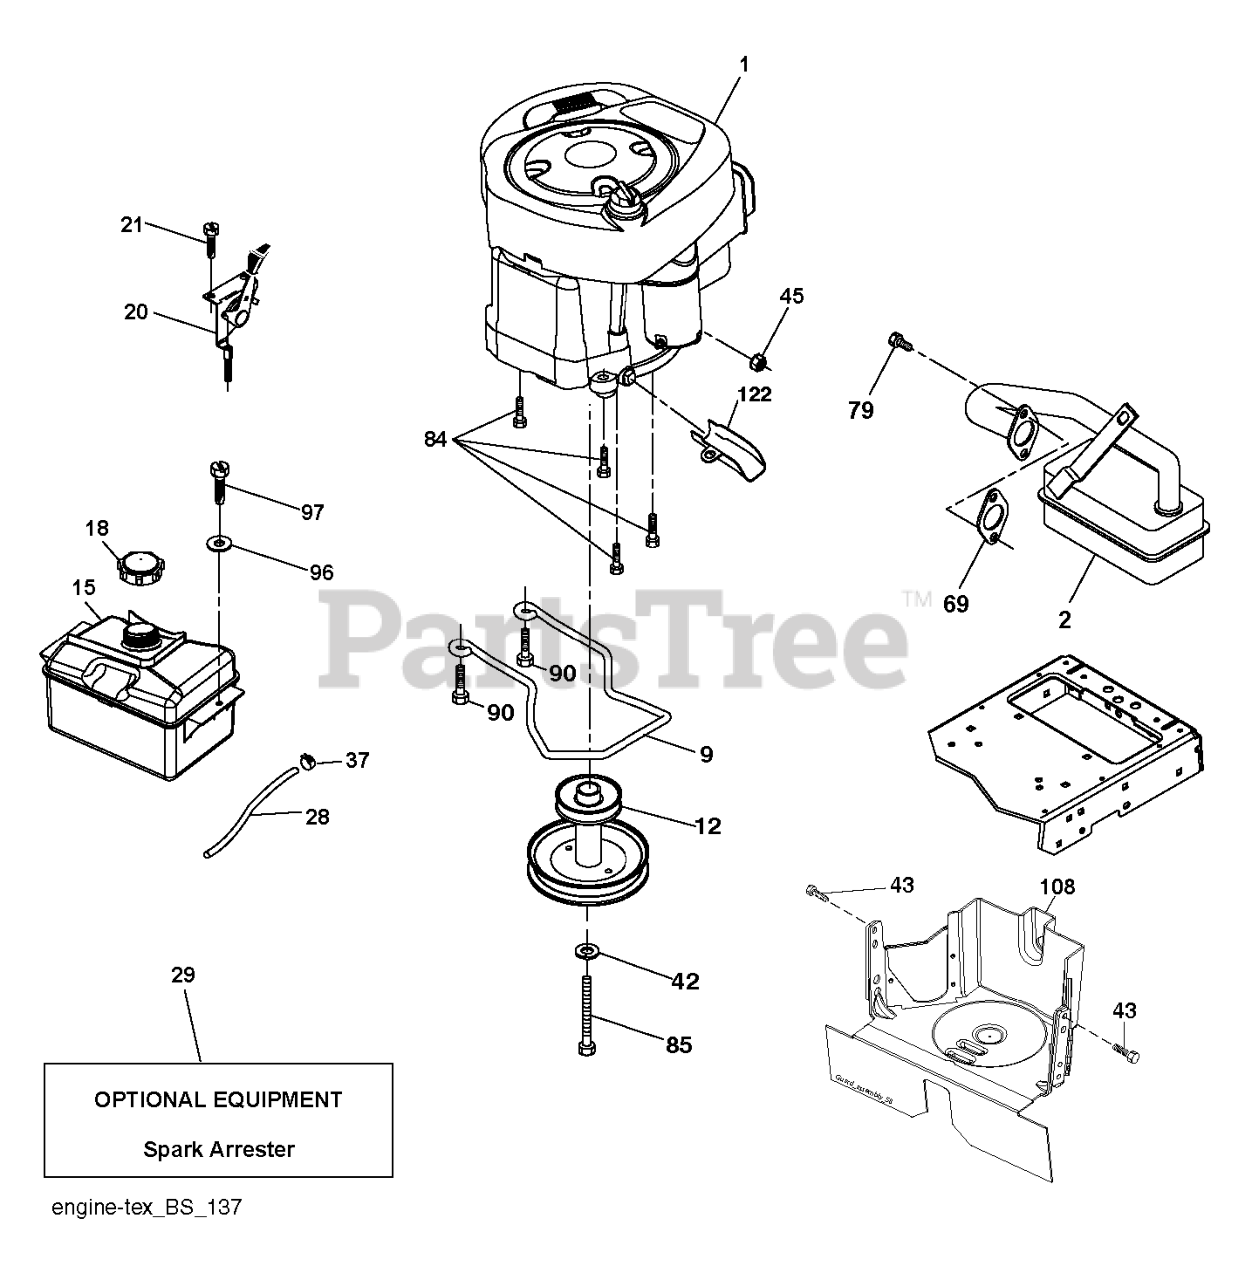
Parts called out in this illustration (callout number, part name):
2	MUFFLER.B&S.MODEL.21.11HP.OHV
9	KEEPER.BELT.ENG.4.25"2.BLT.431
12	ENGINE.PULLEY
15	FUEL.TANK.ASM.NON-EPA
18	CAP ASM.FUEL.2.25"FR.
20	THROTTLE.COBRA.21".RSTART.BLK
28	LINE.FUEL.20
29	KIT.SPARK ARRESTOR 794945 B&S
37	HOSE CLAMP
45	Hardware
69	REPL BY 532 27 22-93
84	SCREW.3/8-16
85	BOLT.HEX.7/16-20X4.GR5.1.5BLUE
90	SCREW 3/8-16X1
97	SCREW HEXWSHR 1/4-20X3/4
108	COVER ENGINE PULLEY COVER WITH
122	EXTENSION DRAIN OIL
